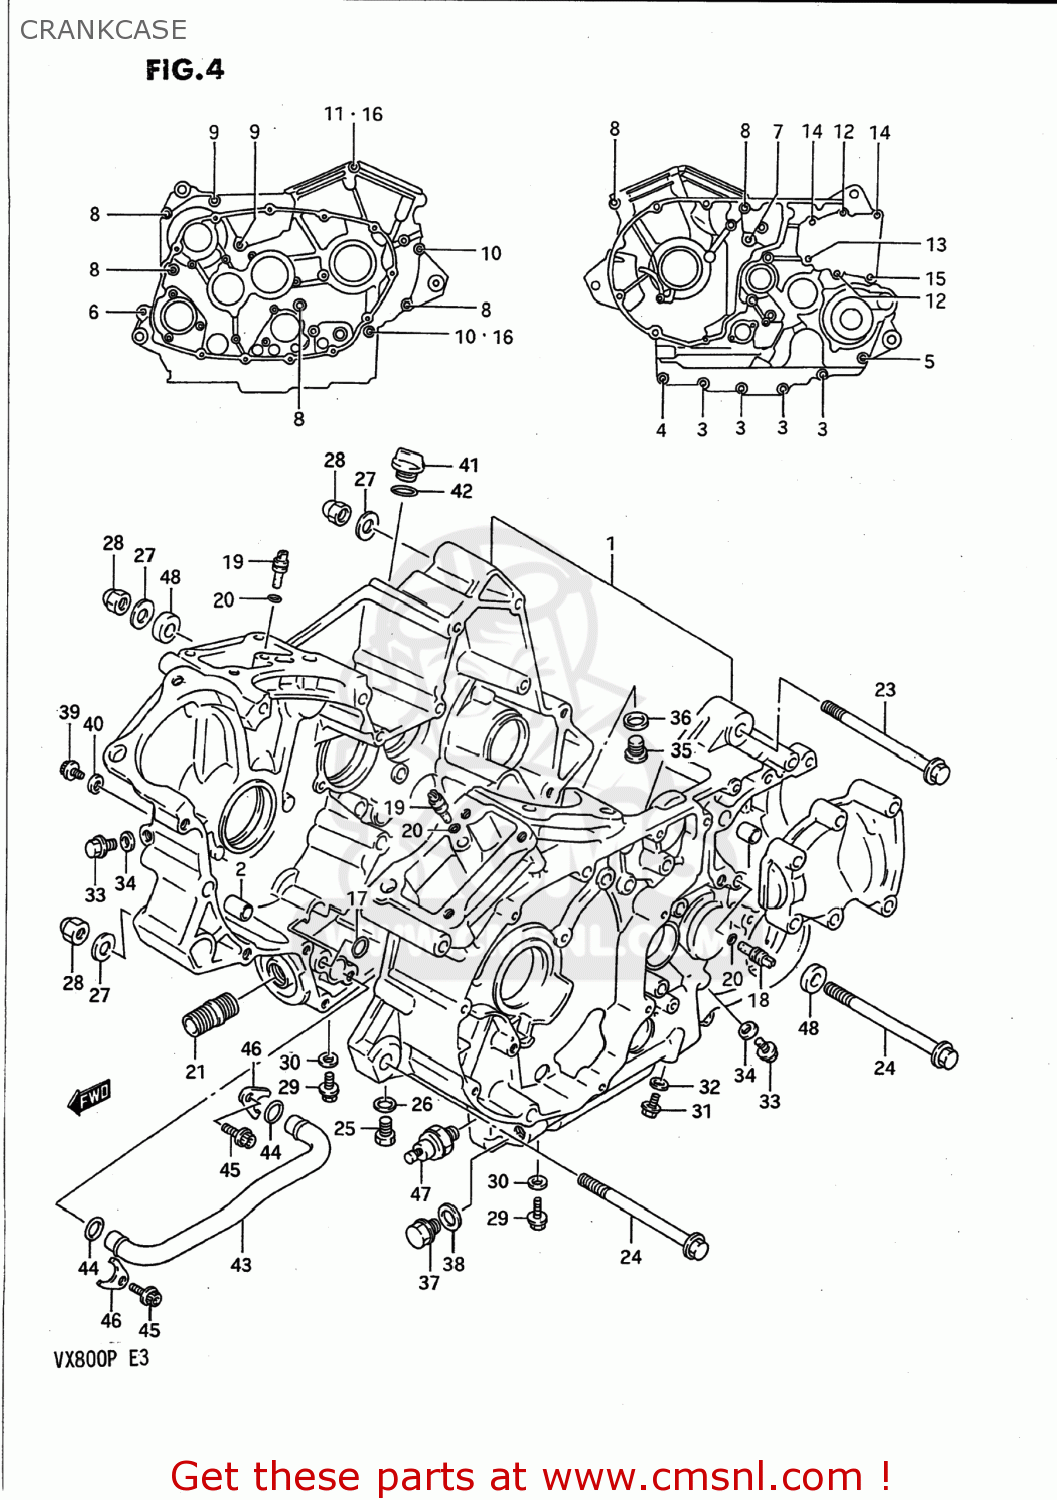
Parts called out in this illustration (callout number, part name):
1	CRANKCASE SET
2	PIN (11X20)(SUS)
3	BOLT
4	BOLT
5	BOLT 8X55
6	BOLT
7	BOLT 8X75
8	BOLT (8X95)
9	BOLT(8X120)
10	BOLT(8X105)
11	BOLT 8X160
12	BOLT 8X40
13	BOLT 8X45
14	BOLT 8X55
15	BOLT 8X65
16	GASKET 8.2X14X1 (NAS)
17	O-RING
18	JET,OIL GALLERY
19	JET,AIR(14)
20	O RING(D:1.2,ID:4)
21	UNION,OIL STAND
22	WASHER(48.1X64X1.94)
23	BOLT(10X130)
24	BOLT,ENGINE MOUNTING (10X170)
25	BOLT
26	GASKET(12.1X16.2X3.7) (NAS)
27	WASHER 10MM
28	NUT
29	BOLT 8X12
30	GASKET(8.2X14X1).6 (NAS)
31	PLUG(10X12)
32	GASKET(10X14X3.6) (NAS)
33	BOLT
34	GASKET(5.8X13X1.2) (NAS)
35	PLUG
36	GASKET(16X22X2) (NAS)
37	PLUG (14X12)
38	GASKET(14X19.2X2) (NAS)
39	BOLT
40	GASKET(8.2X14X1).6 (NAS)
41	PLUG
42	O RING(D:3.1,ID:16.8)
43	PIPE,OIL GALLERY
44	O RING(D:3.1,ID:14.8)
45	BOLT
46	CLAMP,OIL PIPE
47	SWITCH ASSEMBLY
48	SPACER,ENG MOUNT NO.2
